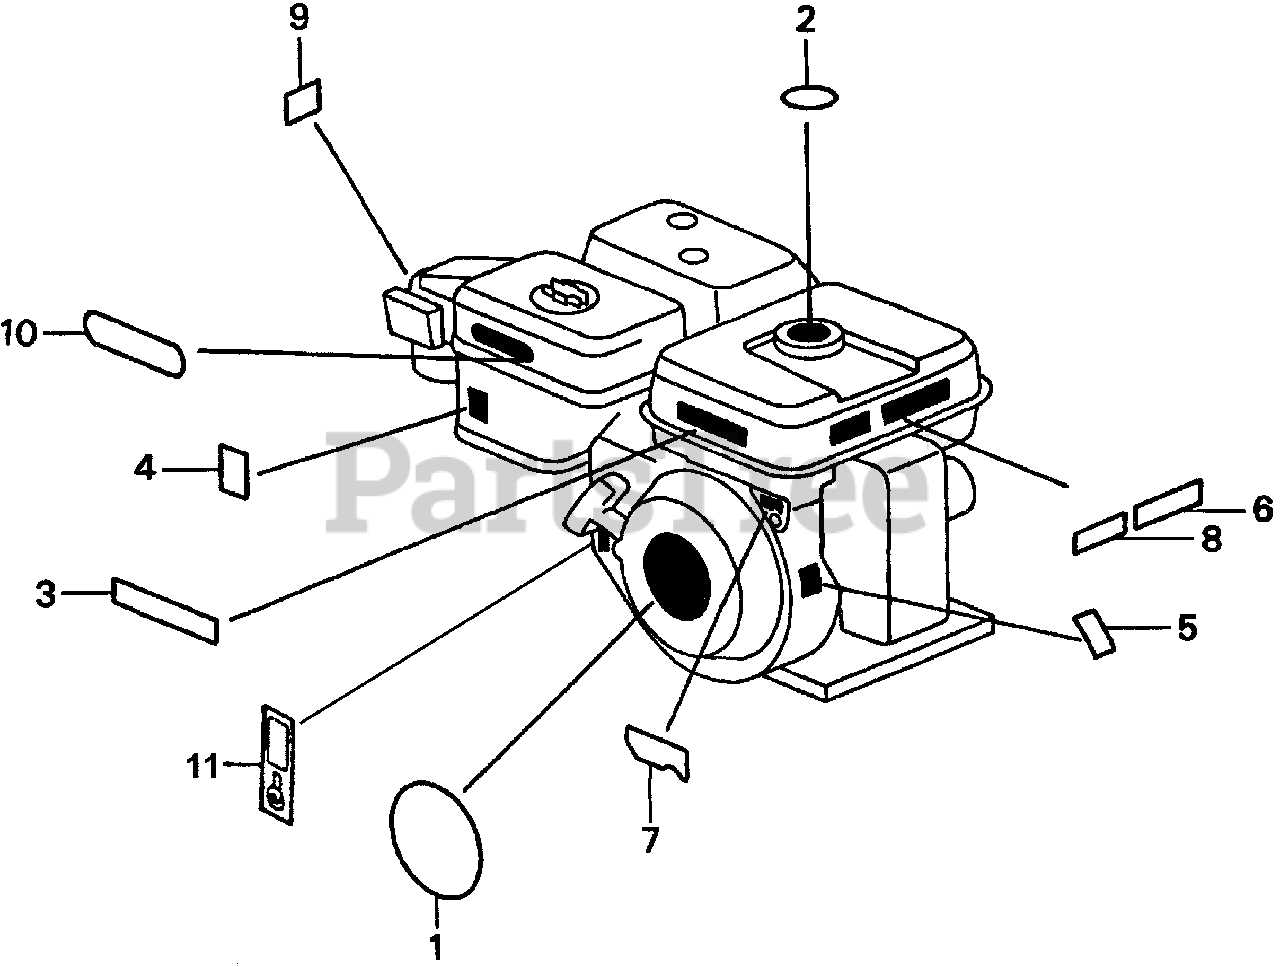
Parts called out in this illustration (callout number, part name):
1	EMBLEM (INTERNAL)
2	MARK, CAUTION (EXTERNAL)
3	LABEL, CAUTION
4	MARK, CHOKE
5	LABEL, SPECIFICATION (EXTERNAL)
6	MARK, OIL ALERT (GERMAN)
6	MARK, OIL ALERT (FRENCH)
7	MARK, OIL ALERT (EXTERNAL)
8	MARK, OIL ALERT (E)
